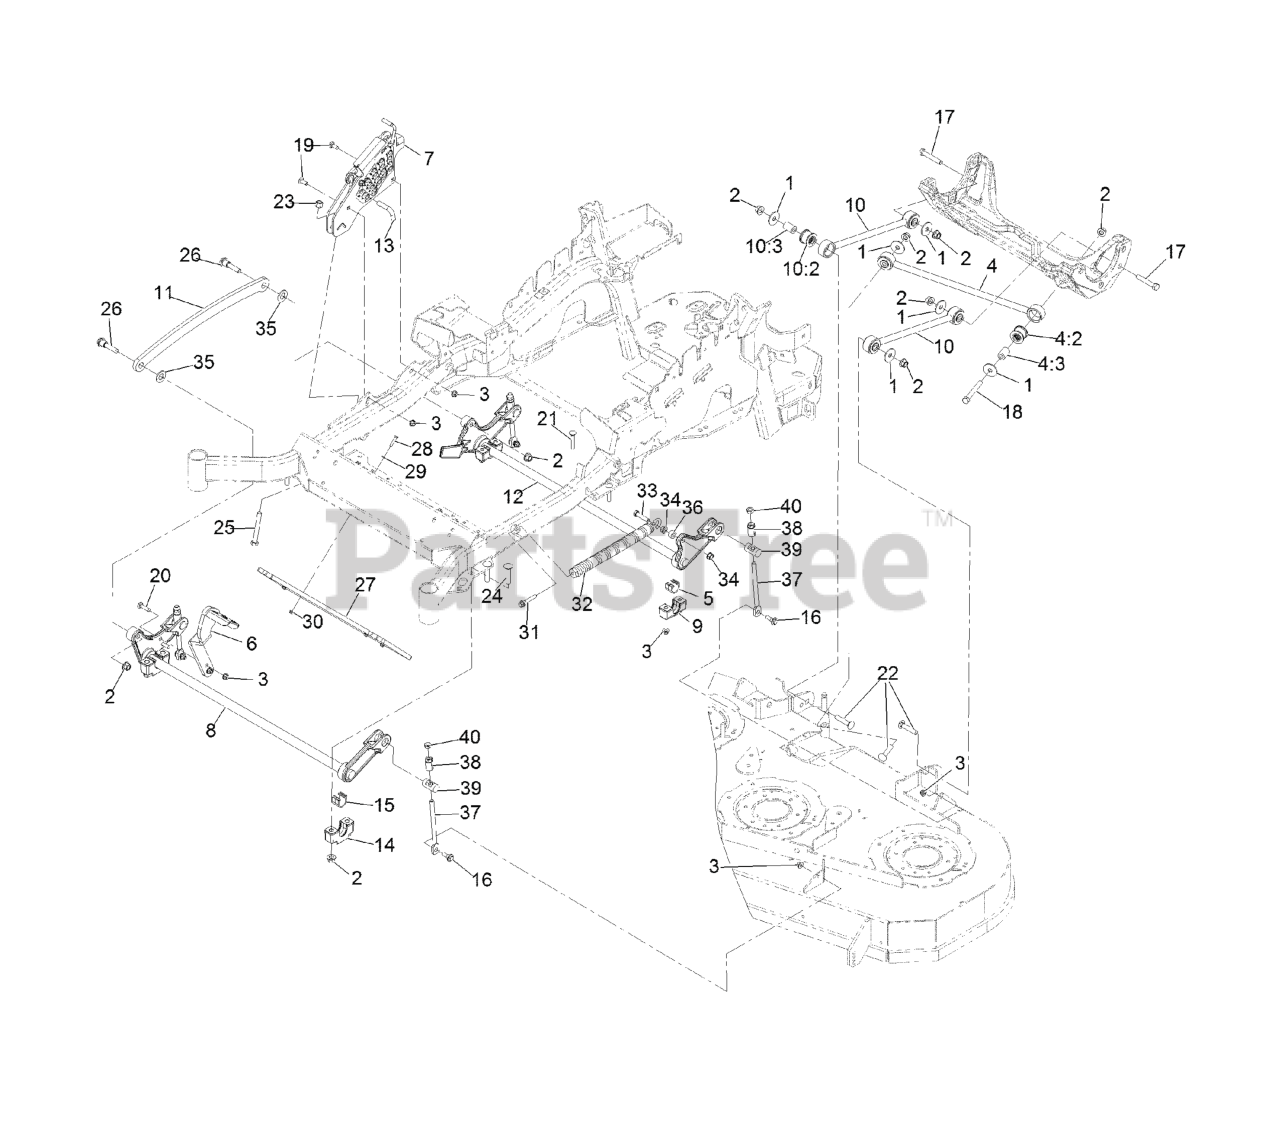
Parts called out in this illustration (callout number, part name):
1	WASHER-THRUST
2	Nut-Lock 1/2-13
3	NUT-HF, NI
4	PANHARD ROD ASM
4:2	BUSHING-SUSPENSION, RUBBER
5	BEARING-CROSS SHAFT, REAR
6	LEVER-FOOT
7	HOC ASM
8	DECKLIFT-FRONT
9	SUPPORT-CROSS SHAFT, BEARING REAR
10	DECK STRUT ASM
10:2	BUSHING-SUSPENSION, RUBBER
11	LINK-LIFT, DECK
12	LIFT-DECK, REAR
13	PIN-HOC
14	SUPPORT-CROSS SHAFT, BEARING
15	BEARING-CROSS SHAFT, FRON
16	SCREW-SHOULDER, HHF
17	SCREW-HH
18	SCREW-HH
19	BOLT-CARR
20	SCREW-CARR
21	Bolt-Carriage 3/8-16 X 2 1/4
22	SCREW-CARR
23	NUT-LOCK, NI
24	Bolt-Carriage 1/2-13 X 2 1/2 Spl Neck
25	BOLT-TAP
26	SCREW-HHF, SHOULDER
27	WEIGHT-TOE BOARD
28	SCREW-HH
29	WASHER-FLAT
31	BOLT-SHOULDER
32	SPRING-EXTENSION
33	SCREW-HH
35	WASHER-FLAT
37	LINK-ADJUSTER, DECK LIFT
38	ADJUSTER-LIFT, DECK
39	TRUNNION
40	NUT-JAM
